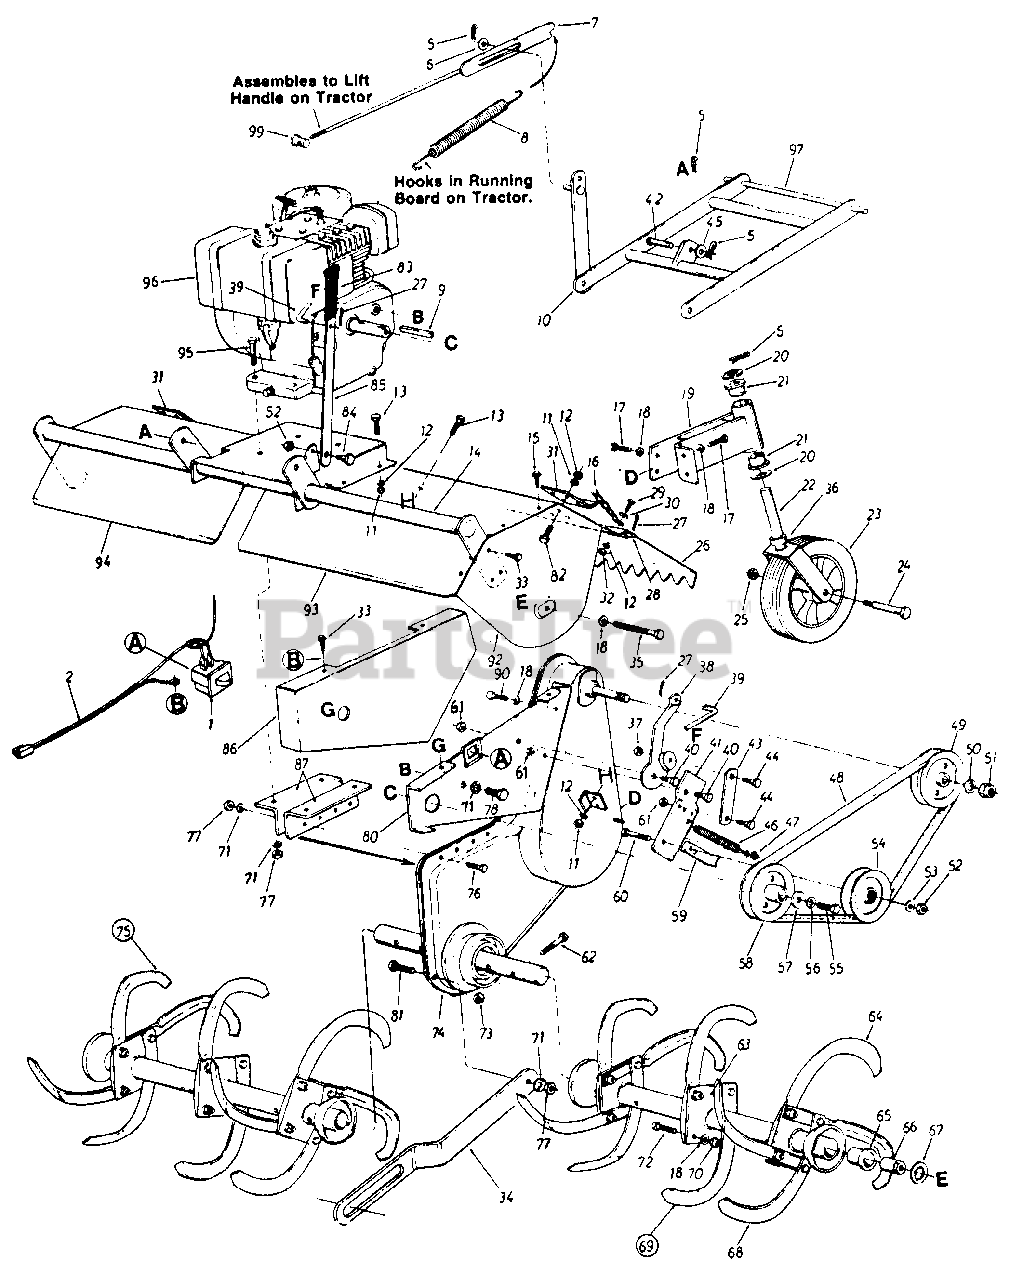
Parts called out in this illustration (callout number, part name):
1	Safety Switch
2	Wire Harness
5	Internal Cotter Pin
6	Fl-Wash. 1/2" I.D. x .93" O.D.
9	Sq. Key 1/4" X 1/4" X 2.00" Lg.
12	L-Wash. 1/4" I.D.'
13	Hex Bolt 1/4-28 x .62" Lg.
16	#2 Dog Chain x 20 Lg.
17	Hex Wash. Hd. Self-Tap Scr. 3/8-24 x . 75 " Lg .
18	L-Wash. 3/8" I.D.
19	Swivel Wheel Support
20	Fl-Wash. 3/4" I.D. x 1.50" O.D.
21	Flange Bearing 3/4" I.D. x 1.00" O.D.
22	Swivel Wheel Caster
23	Wheel Assembly 10.0 x 2.75
24	Shoulder Bolt .623" I.D. x 3.62" Lg.
25	Hex Cent. L-Nut 7/16-14 Thd.
28	L.H. Flap Rod
28	R.H. Flap Rod
29	Hex Bolt 1/4-20 x .62" Lg.
30	Fl-Wash. 1/4" I.D.
33	Hex Wash. Hd. Self Tap Scr. 1/4" x.62" Lg.
34	Stabilizer Link
35	Hex Bolt 3/8-16 x 1.25" Lg.
36	Spacer .752" I.D. x 1.25" O.D.
37	Hex Cent. L-Nut 5/16-18 Thd.
40	Shoulder Bolt 7/16" Dia. x 1.75" Lg.
45	Fl-Wash. .50" I.D. x 1.0" O.D. x .06
46	Extension Spring .62" O.D. x 6.12" Lg.
47	Hex Crown Nut 3/8-24 Thd.
48	V-Belt (Kevlar)
49	1/2" "V"-Pulley 4.75" O.D. x .625" Bore
50	L-Wash. 5/8" I.D.
51	Hex Ins. L-Nut 5/8-18 Thd.
52	Hex Cent. L-Nut 3/8-16 Thd.
53	Fl-Wash. 3/8" I.D.
54	Idler Pulley 4.0" O.D.
55	Hex Bolt
56	L-Wash. 7/16" I.D.
57	Fl-Wash. 7/16" I.D. x 1.38"
58	1/2" "V"-Pulley .475" O.D. x 1.00" Bore
61	Hex Cent. L-Nut 5/16-18 Thd.
62	Hex Bolt 7/16-14 x 2 00n Lg.
65	Flange Bearing 1.00" I.D.
66	Spacer
67	Thrust Wash. 1/2" I.D. x 1.55"
68	Tine-R. H .
69	Tine Assembly Comp.-L.H.
70	Hex Nut 3/8-24 Thd.
71	L-Wash. 5/16" I.D.
72	Hex Bolt 3/8-24 x 1.5" Lg.
73	Hex Cent. L-Nut 7/16-14 Thd.
77	Hex Nut 5/16-18 Thd.
78	Hex Bolt 5/16-24 x .62"
80	Clutch Support Bracket
81	Shld. Bolt .435 Dia. x .265 0 5/16-18 Thd.
82	Hex Bolt 1/4-28 x .75" Lg.
83	Plastic Grip
84	Shoulder Bolt .498 Dia. x .212 Lg.
87	Engine Mounting Bracket
90	Hex Bolt 3/8-16 x .62" Lg.
92	L.H.-Side Plate
96	8 H.P. Engine
97	Hitch Rod
99	Ferrule
